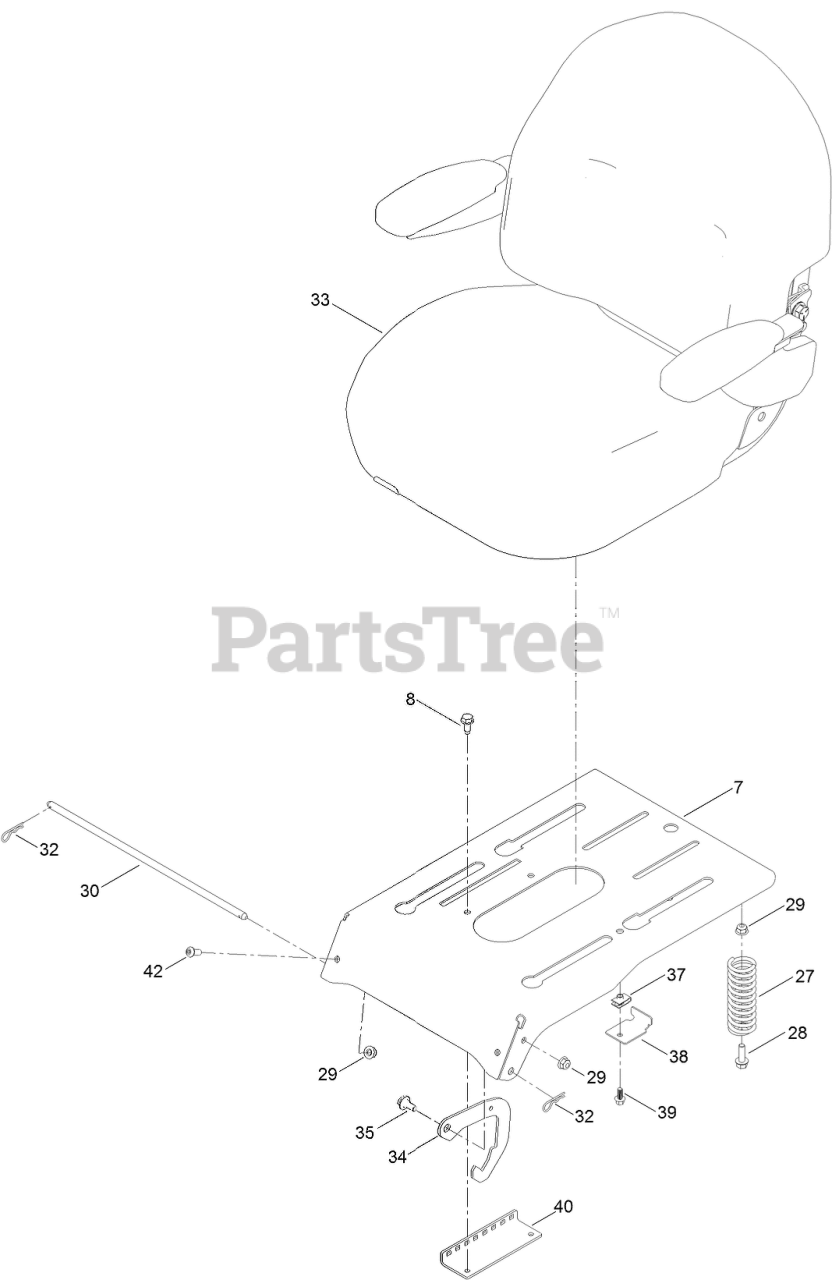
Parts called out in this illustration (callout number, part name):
7	PAN-SEAT, DELUXE
8	SCREW-HWHTF
27	SPRING-COMPRESSION
28	SCREW-HHF
29	NUT-HF
30	ROD-PIVOT, NARROW
32	PIN-COTTER
33	SEAT ASM
34	SEAT LATCH
35	SCREW-SHOULDER
38	BRACKET-STOP, SEAT
39	SCREW-HHF
40	BRACKET-LATCH, SEAT
42	SCREW-HSBH
